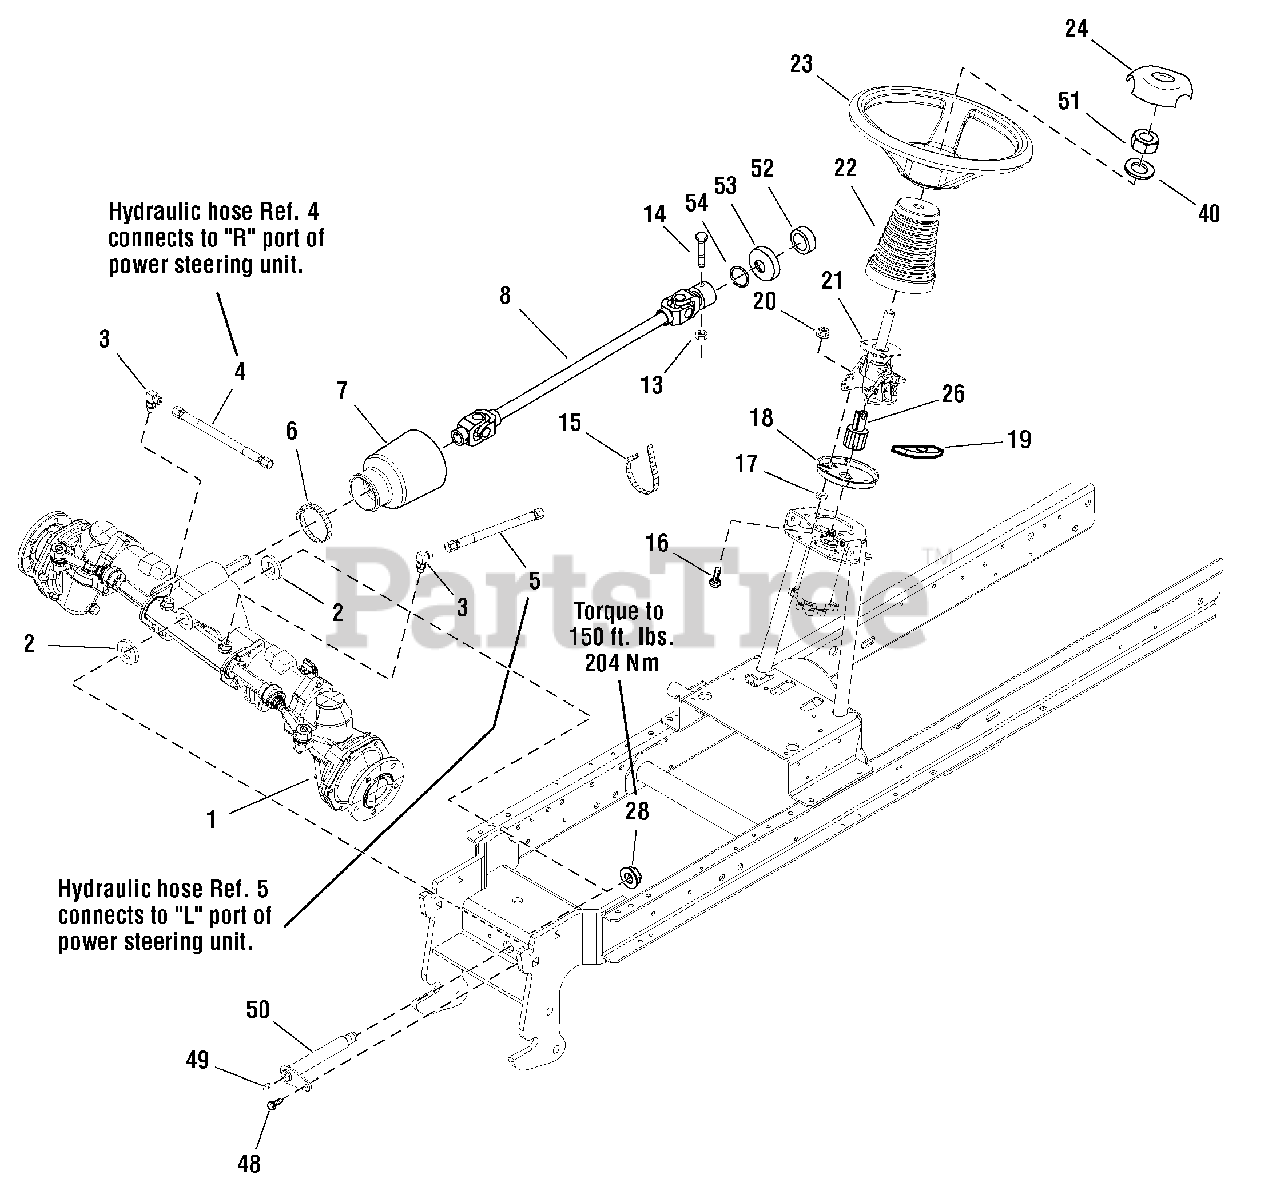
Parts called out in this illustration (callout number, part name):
1	AXLE ASSSEMBLY
3	FITTING, Elbow Hose
4	HOSE ASSEMBLY, Hydraulic
5	HOSE ASSEMBLY, Hydrualic
6	CLAMP, Worm Hose
7	COVER, Drive Shaft
8	SHAFT ASSEMBLY
13	NUT, Hex, Lock, 3/8-16 NC
14	CAPSCREW, Hex Head, 3/8-16 x 1-3/4 G5
15	TIE, Self Locking
16	BOLT, Carriage, 5/16-18 x 1 1/4
17	NUT, Push, 1/4
18	PLATE, Steering
19	SPACER, Flat
20	NUT, Hex, Keps 5/16-18 Black
21	TILT STEERING UNIT, Legacy
22	BELLOWS, Tilt Steering Unit With Slot
23	STEERING WHEEL
24	CAP, Steering Wheel
26	ADAPTER TILT, 9 Tooth With Powerdered Metal
28	NUT, Hex, Toplock Flange 3/4-10
40	WASHER, 5/8
48	SCREW, Hex Washer Head, Taptite, 5/16-18 x 3/4
49	FITTING, Lube, 1/4 Drive
50	SHAFT & ANCHOR ASSEMBLY, Pivot
51	NUT, Hex Lock, ESNA Light, 5/8-18
52	SPACER, 0.793 x 1-3/4 x 1/4
53	CUP, Grass Shield
